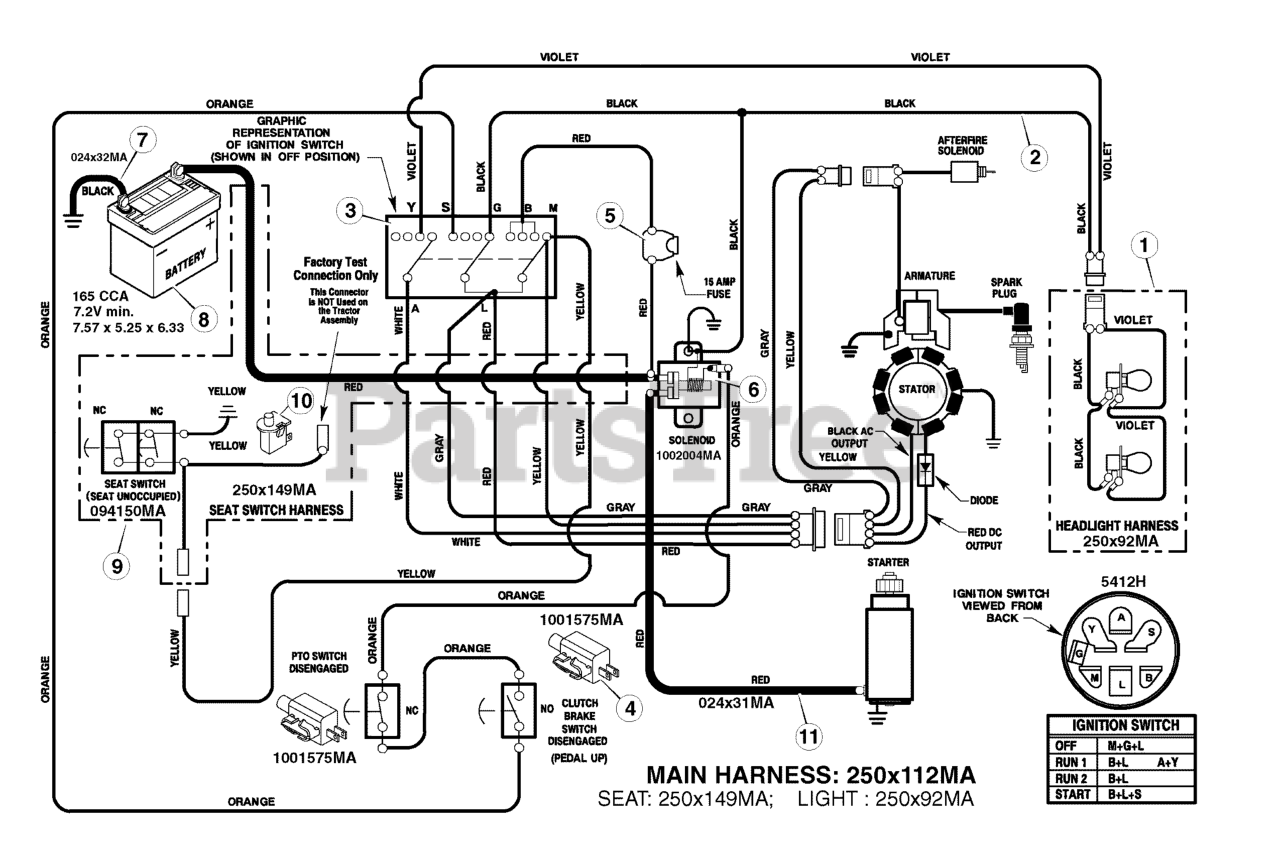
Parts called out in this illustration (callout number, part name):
1	HARNESS, Headlight
2	HARNESS, Chassis Wire
3	SWITCH, Ignition, Indak
4	SWITCH, No Limit, Snap-In
6	SOLENOID, 3 Pole
7	CABLE, Battery Ground
8	BATTERY, 12 Volt, 230 CCA
9	WIRING HARNESS, Seat Switch
11	CABLE, Battery
